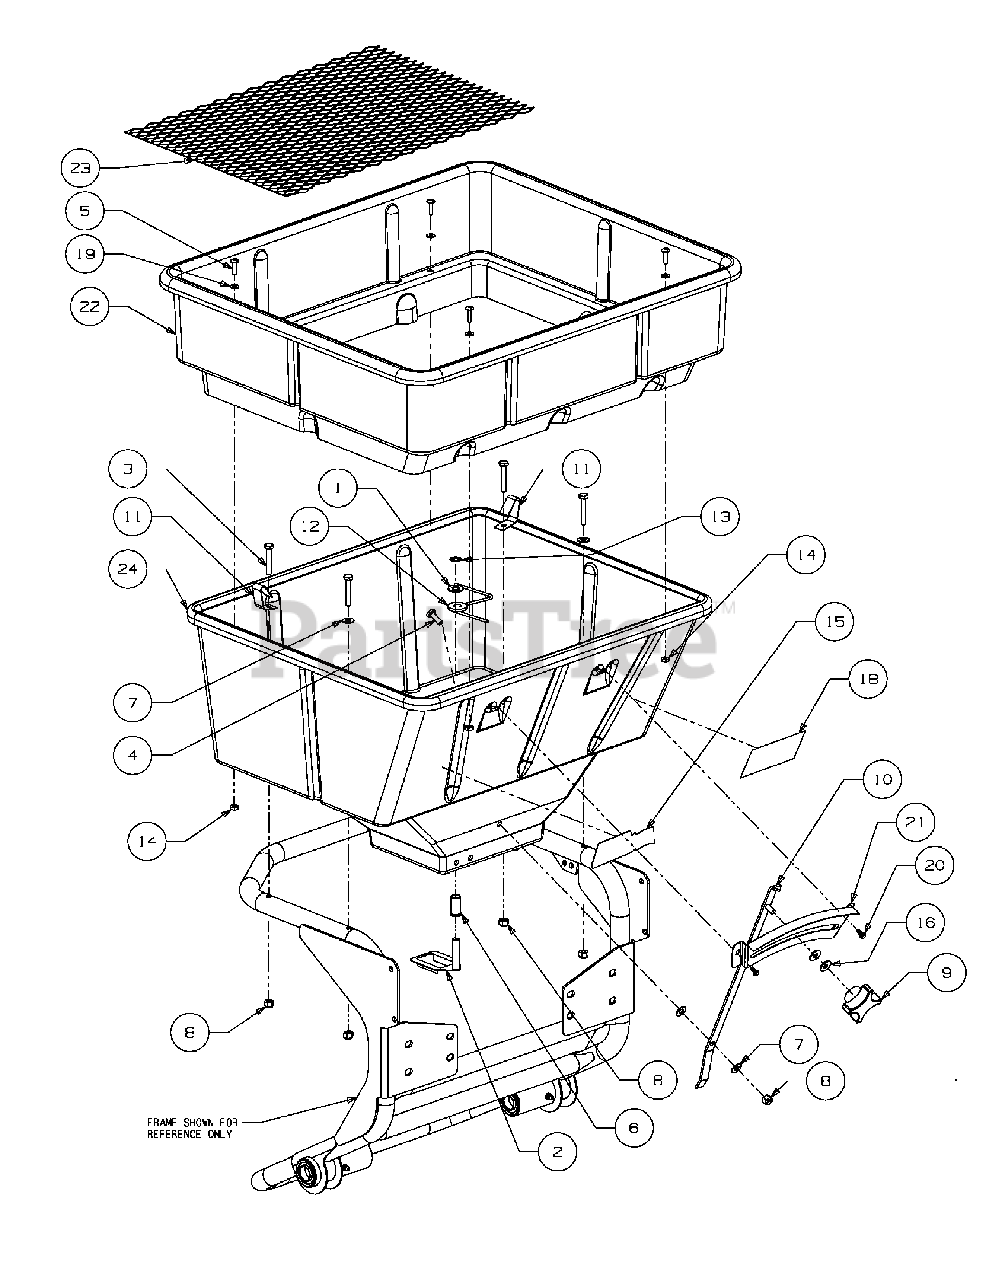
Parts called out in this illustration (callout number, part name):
1	Washer-Flat Nylon
2	Cam-Agitator SS
3	Screw-Hex Cap 1/4
4	Screw-Hex Cap 1/4
5	Screw-Pan Hd 10-24
6	Bearing-Agitator S
7	Washer-Flat SS
8	Nut-Nylon Lk 1/4
9	Knob-Rate Control
10	Arm-Rate Control
11	Clip-Screen SS
12	Arm Assy-Agitator
13	Clip-Spring
14	Nut-Hex Lock SS #1
15	Label-Made N America
16	Washer-Flat Nylon.
17	Cover-100 Lb Hopper
18	Label-80# Capacity
19	Washer-Flat
20	Screw-Hex #8 X 3/8
21	Plate-Rate
22	Hopper-Black
23	Screen
24	Hopper-Black
